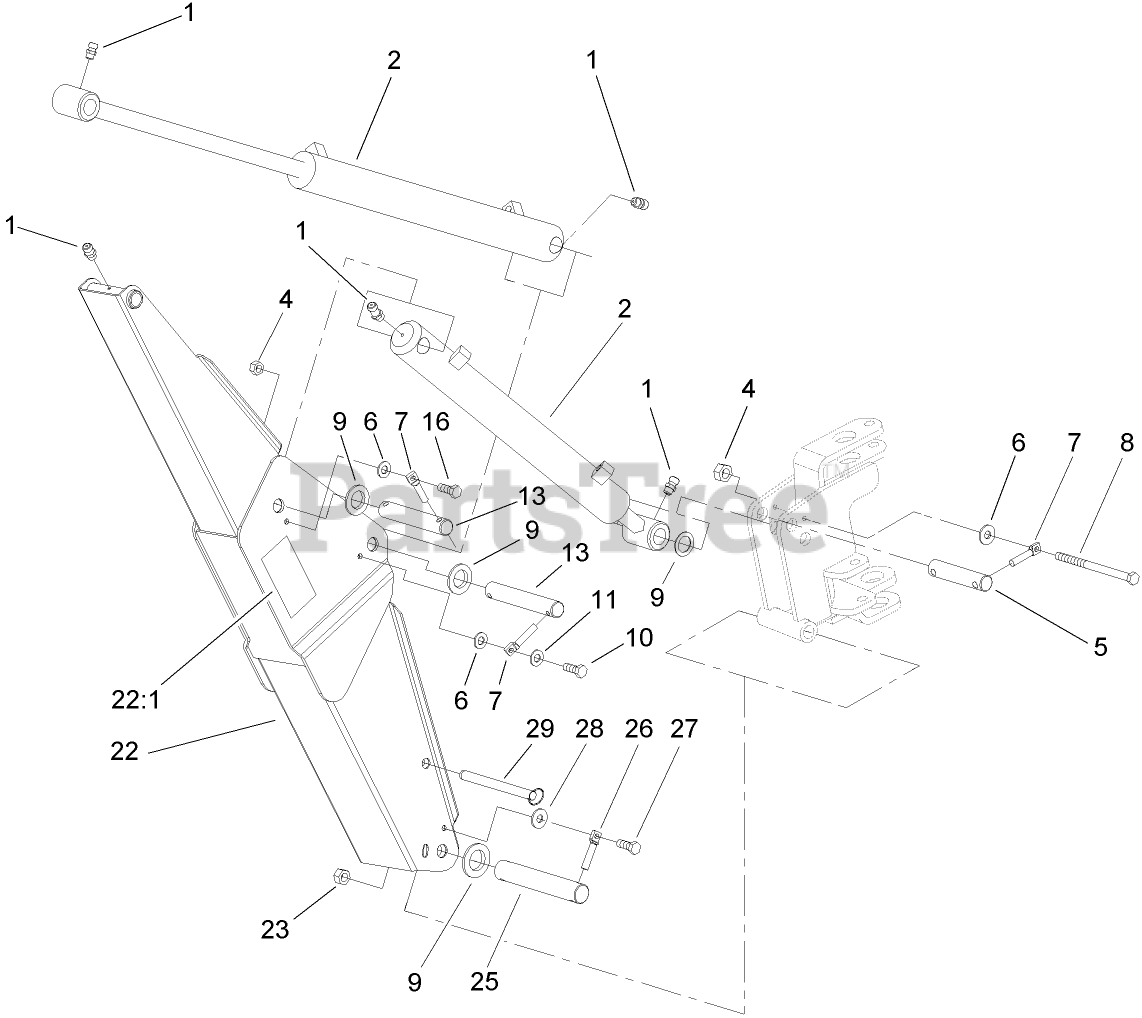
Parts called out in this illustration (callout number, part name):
1	FITTING-GREASE
2	HYDRAULIC CYLINDER ASM
4	NUT-LOCK
5	PIN-PIVOT
6	WASHER-PLAIN
7	PIN-RETAINER, SMALL
8	SCREW-HH
9	WASHER-FLAT
10	SCREW-HH
11	WASHER-LOCK
13	PIN-PIVOT
16	SCREW-HH
22	BOOM ASM
22:1	DECAL-WARNING
23	NUT-LOCK
25	PIN-PIVOT
26	PIN-RETAINER, LARGE
27	SCREW-HH
28	WASHER-FLAT
29	PIN-HITCH
